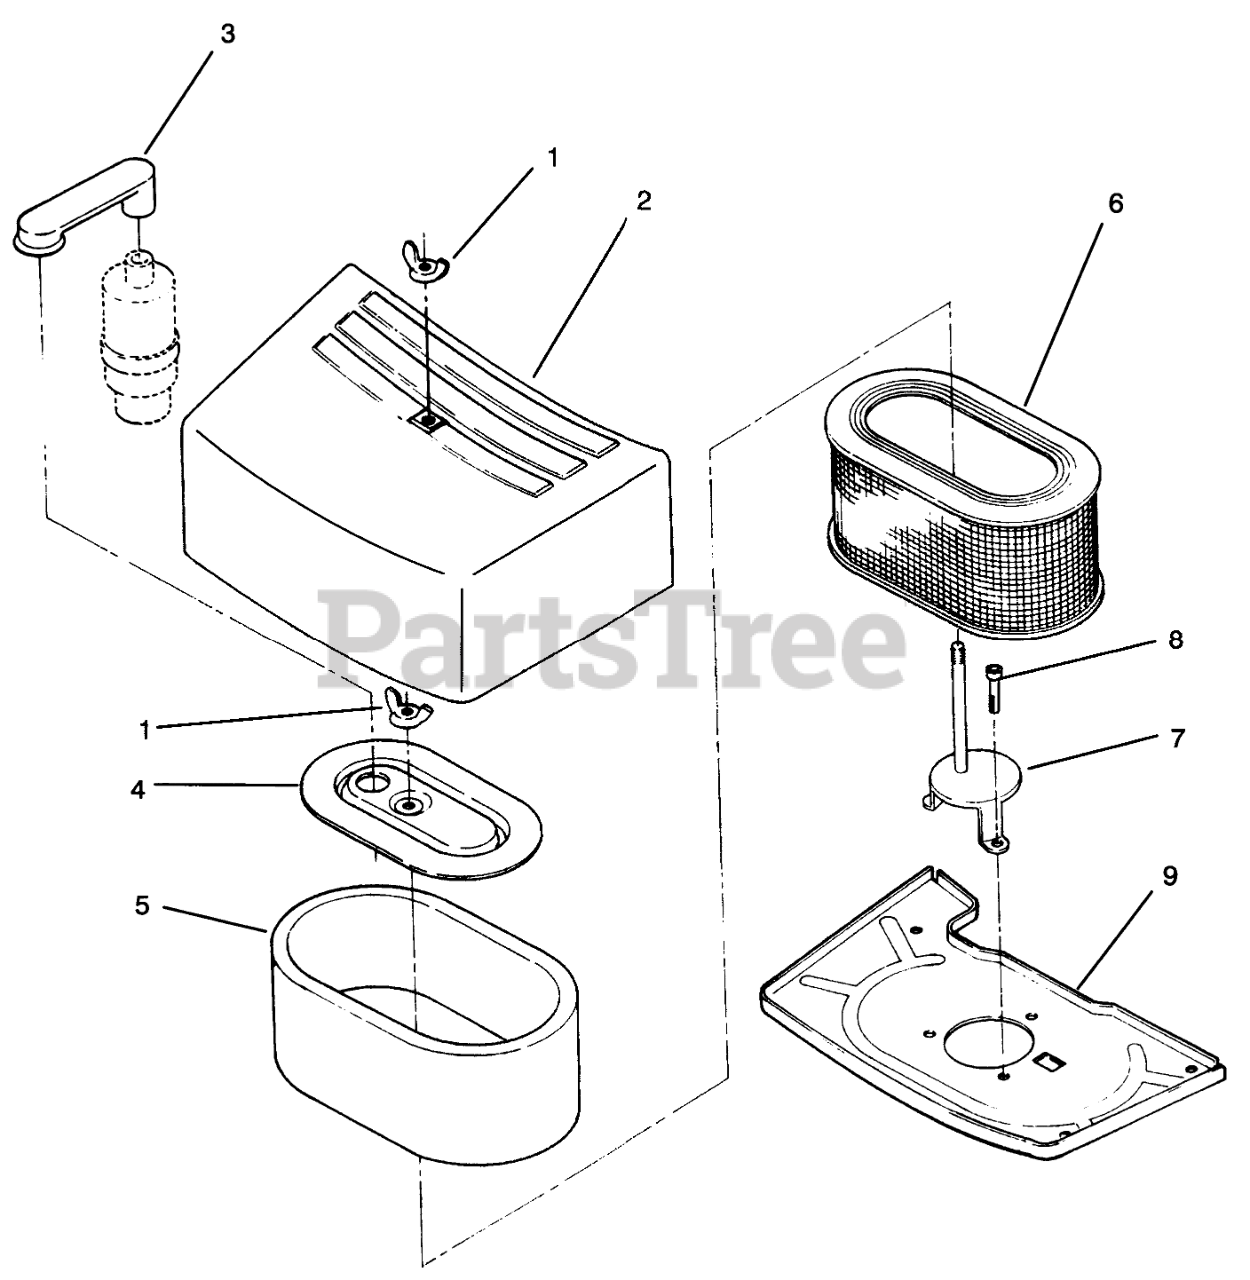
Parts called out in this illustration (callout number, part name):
1	Nut-Wing
3	BREATHER-TUBE
4	ELEMENT-COVER (ZINC)
5	ELEMENT-WRAPPER
6	ELEMENT
7	HOOD-SUPPORT
8	SOCKET-HEAD CAP SCRW
9	PAN (ZINC)
